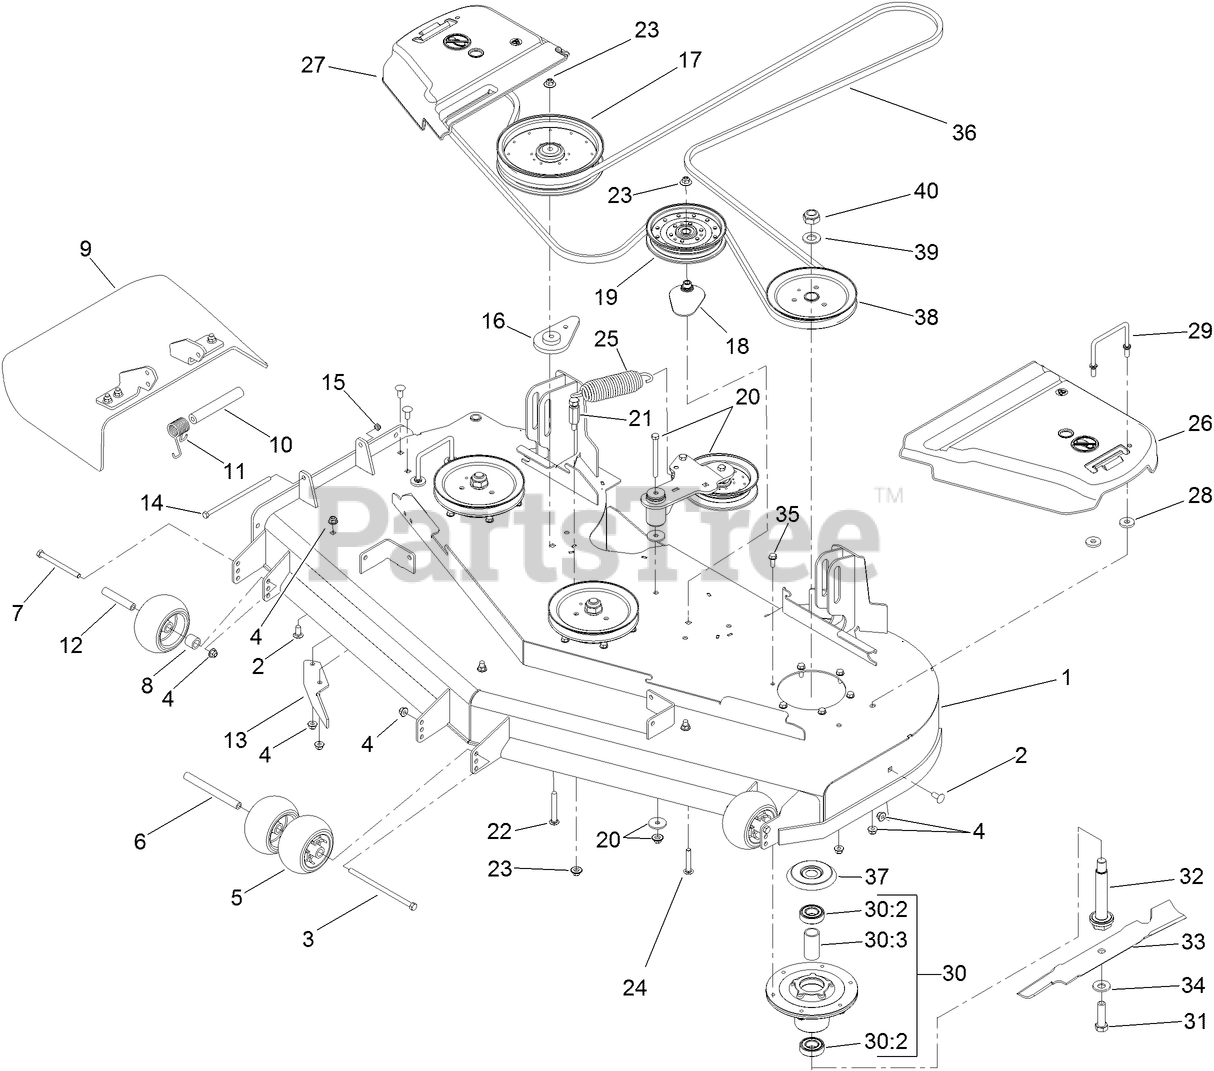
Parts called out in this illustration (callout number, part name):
1	DECK DECAL ASM
2	SCREW-CARR
3	SCREW-HH
4	NUT-HF, NI
5	ROLLER-SCALP, ANTI
6	SPACER-WHEEL
7	SCREW-HH
8	TUBE-SPACER
9	DEFLECTOR ASM
10	SPACER
11	SPRING-TORSION
12	TUBE-SPANNER
13	BAFFLE-DISCHARGE
14	SCREW-HH
15	NUT-LOCK, NI
16	SPACER-IDLER
17	PULLEY-IDLER
18	SPACER-PULLEY
19	PULLEY-IDLER, FLAT
20	IDLER ARM ASM
21	ANCHOR-SPRING, TALL
22	SCREW-CARR
23	NUT-FLANGE, NI
24	BOLT-CARR, SHORT NECK
25	EXTENSION-SPRING
26	COVER-BELT, LH
27	COVER-BELT, RH
28	WASHER
29	WIREFORM-COVER
30	SPINDLE ASM
30:2	BEARING-BALL
30:3	SPACER-BEARING
31	SCREW-BLADE
32	SPINDLE-SHAFT
33	BLADE-HI FLOW, 20.5 INCH
34	WASHER-BELLEVILLE
35	SCREW-TAPTITE
36	BELT-V
37	SHIELD-BEARING
38	PULLEY B SECTION
39	WASHER
40	NUT-LOCK, NI
